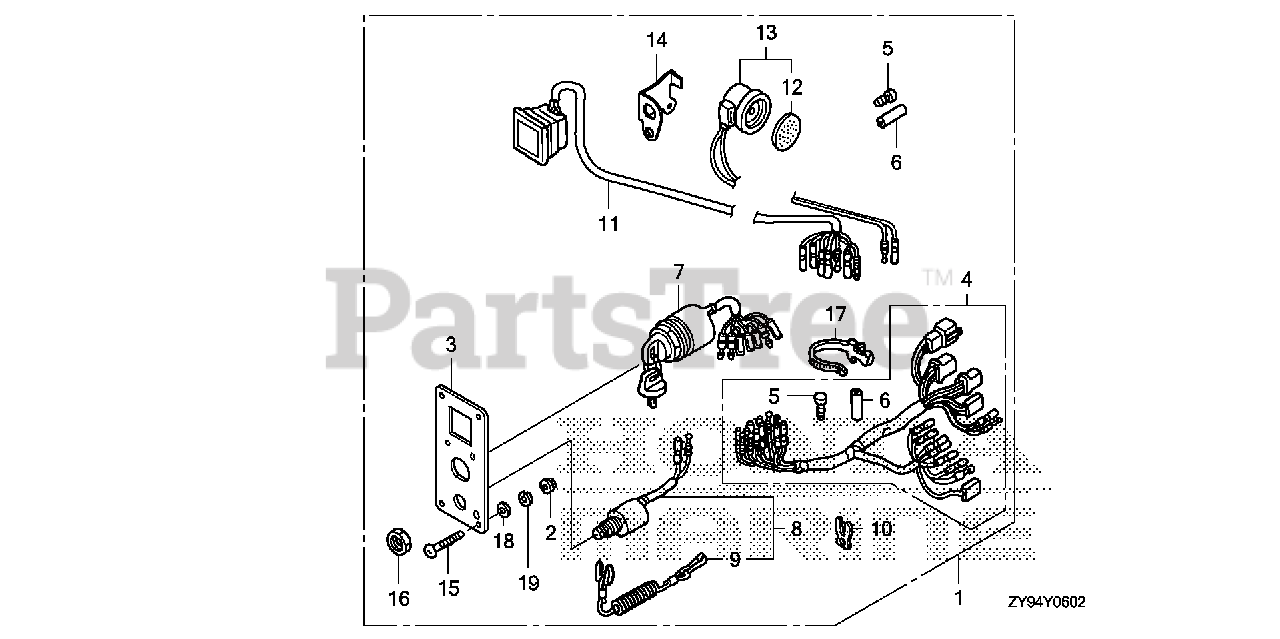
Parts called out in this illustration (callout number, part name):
1	PANEL KIT, SWITCH (4-LED)
2	NUT, FLANGE (5MM) DUAL QTY = (8) (SINGLE)
3	PANEL, CONTROL
4	HARNESS ASSY., SWITCH PANEL
5	PLUG, CONNECTOR (INNER) (TROLLING CONTROL)
6	PLUG, CONNECTOR (OUTER) (ENGINE NO.)
7	SWITCH ASSY., COMBINATION (SINGLE) (DUAL)
8	SWITCH ASSY., EMERGENCY STOP
9	WIRE, EMERGENCY (SINGLE) (DUAL)
10	CLIP, EMERGENCY LOCK
11	LAMP ASSY., INDICATION (4-LED)
12	PLATE, TURN SIGNAL BUZZER DUAL QTY = (2) (SINGLE)
13	BUZZER, WARNING DUAL QTY = (2) (SINGLE)
14	BRACKET, BUZZER
15	SCREW, PAN (5X40) DUAL QTY = (8) (SINGLE)
16	NUT, HEX. (16MM) DUAL QTY = (2) (SINGLE)
17	BAND, WIRE HARNESS (150MM) (NATURAL) DUAL QTY = (2) (SINGLE)
18	WASHER, PLAIN (5MM) DUAL QTY = (8) (SINGLE)
19	WASHER, SPRING (5MM) DUAL QTY = (8) (SINGLE)
